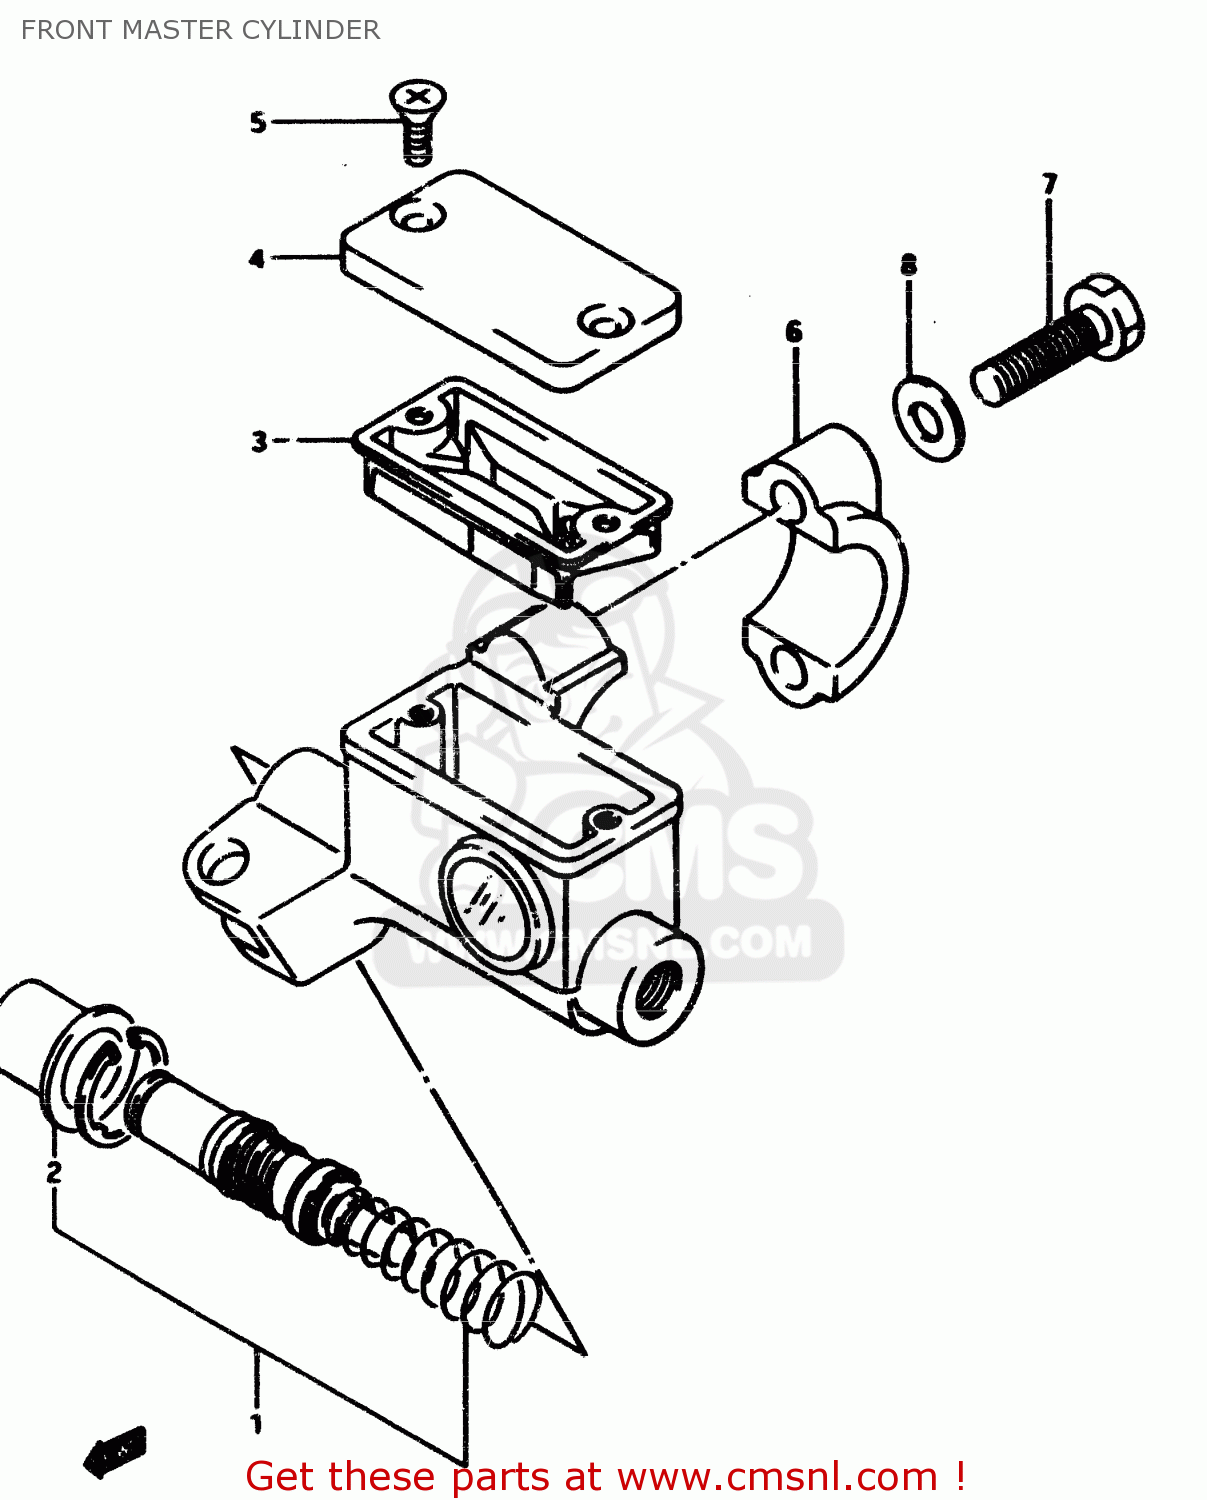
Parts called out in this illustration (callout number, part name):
1	PISTON/CUP SET,FR MASTER
2	BOOT
3	DIAPHRAGM
4	CAP
5	SCREW
6	HOLDER,MASTER CYLINDER
7	BOLT
8	WASHER
